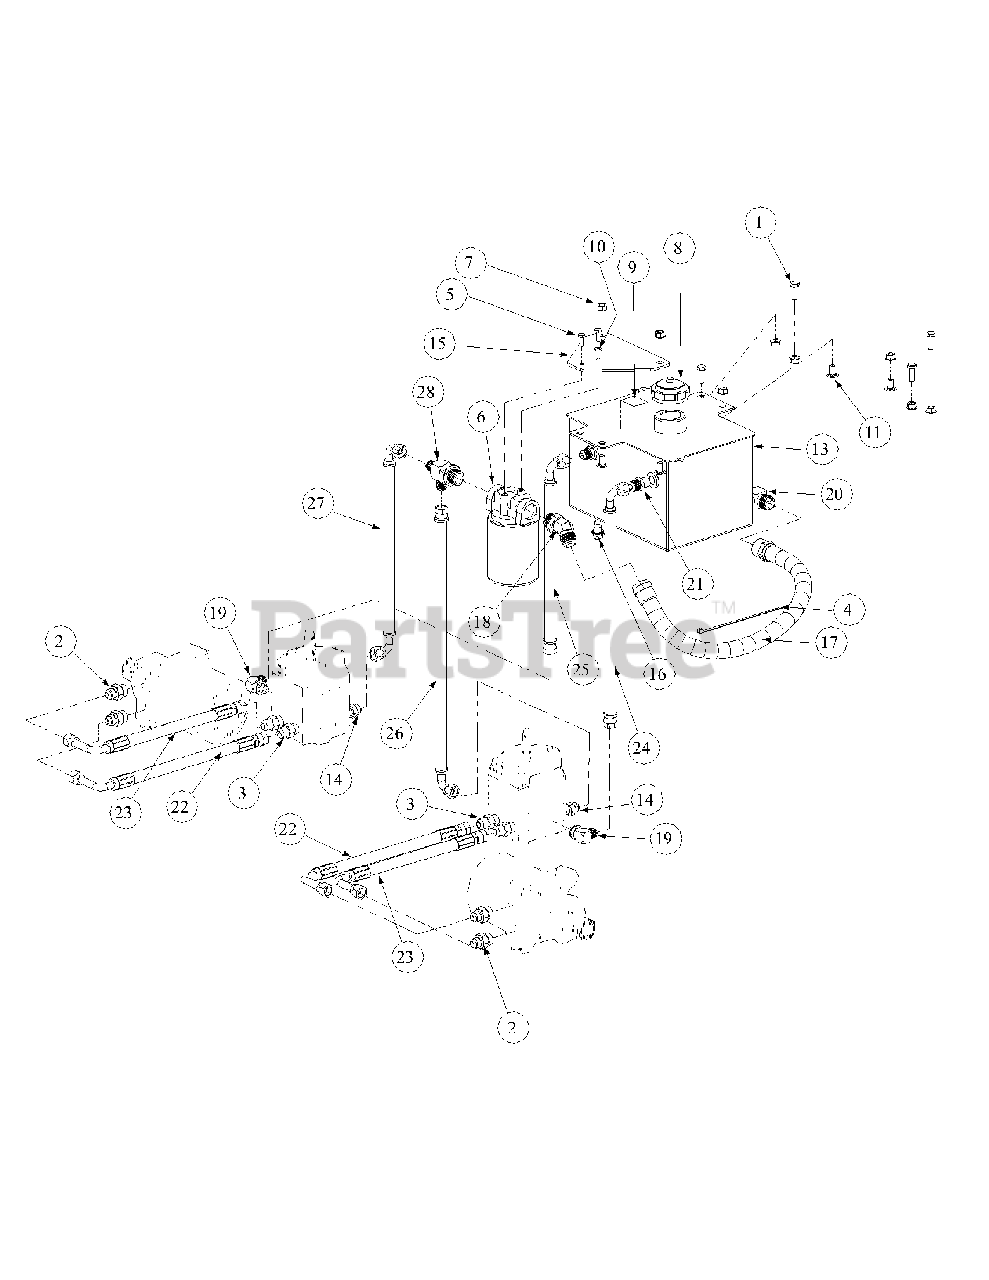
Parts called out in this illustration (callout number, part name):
1	Hex Cap Screw, 3/8-16, 1
2	Fitting 1/2 x 3/4 - O Ring
3	Fitting 1/2 x 3/4 - O Ring to Flare
4	Cable Tie, 3/16 x .05 x 7.4
5	Hex Cap Screw, 1/4-20, .75
6	Filter Head 3/4
7	Hex Nut Flange Lock, 3/8-16
8	Cap, Hydro Oil Tank
9	Decal Oil Only 20W50
10	Lock Washer, 1/4
11	Carriage Bolt, 3/8-16 x .75 LG.
13	Hydraulic Tank Assembly
14	Fitting Connector, 1/2 x 3/8
15	Oil Filter Mounting Plate
16	Oil Pan Drain w/ Seal and Plug
17	Tank to Filter Hose Assembly
18	Connector, 3/4 x3/4
19	Elbow Fitting, 3/8 O-ring, 1/2 Flare
20	Fitting Elbow, 1/2 x 1/2
21	Fitting, 3/8 NPT, 1/2 Flare
22	Long Pressure Hose Assembly
23	Short Pressure Hose Assembly
24	17.75" Return Hose Assembly, RH
25	14" Return Hose Assembly, LH
26	21.25" Supply Hose Assembly, RH
27	15.50" Supply Hose Assembly, LH
28	Tee Fitting, 3/4 x 1/2 x 1/2
